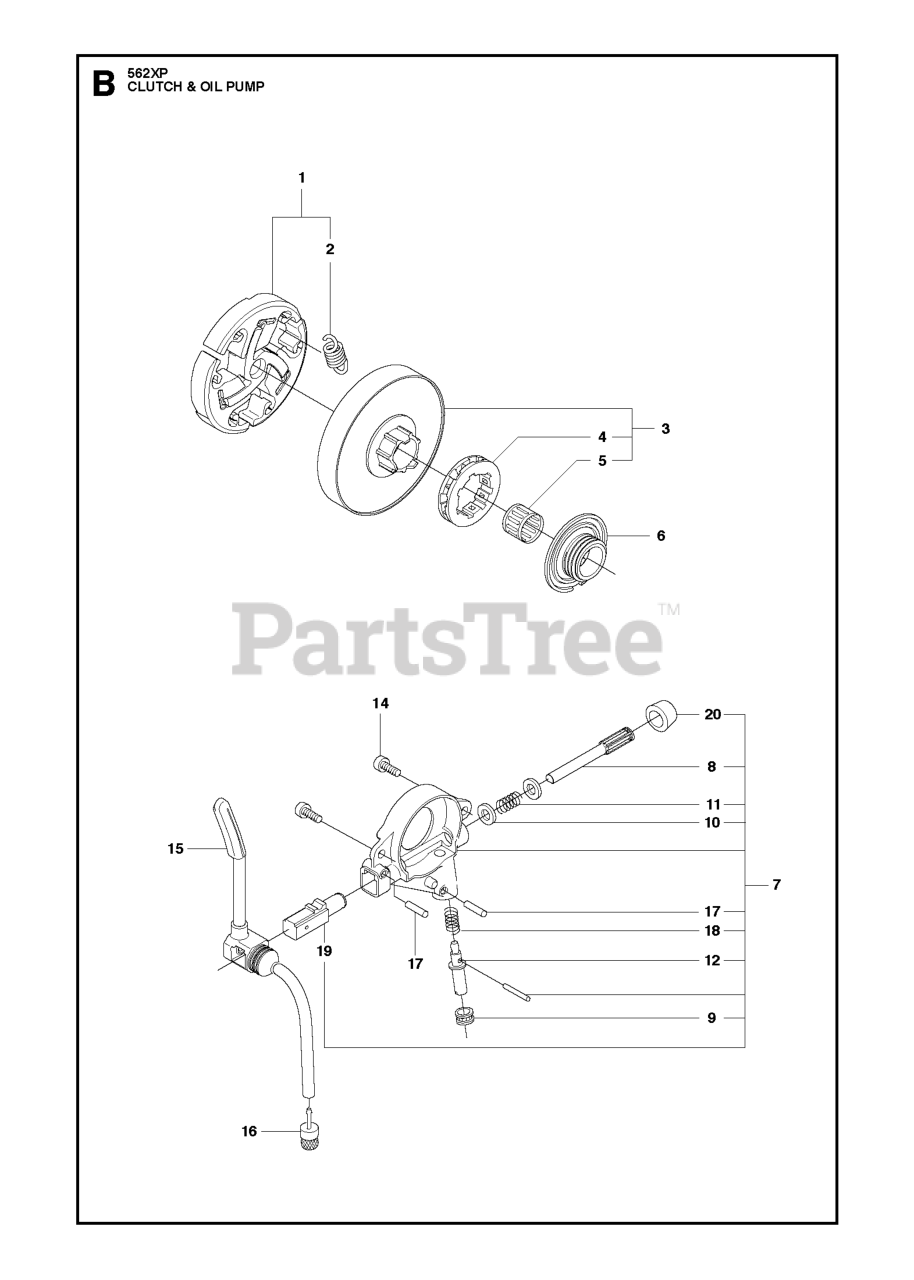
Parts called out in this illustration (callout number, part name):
1	CLUTCH ASSY
2	CLUTCH SPRING
3	CLUTCH DRUM ASSY
3	CLUTCH DRUM ASSY 3/8 (7T)
4	RIM SPROCKET 7T .325
4	68210 RIMSPROCKET
5	SUPPORT BUSHING
6	RP WORM WHEEL
7	OIL PUMP ASSY
8	PUMP PISTON
9	CASING
10	WASHER
11	SPRING
12	ADJUSTING SCREW
14	SCREW IHSCM
16	OIL PLUMMET
17	PIN 3X10
18	SPRING
19	PUMP CYLINDER
20	SEALING PLUG
